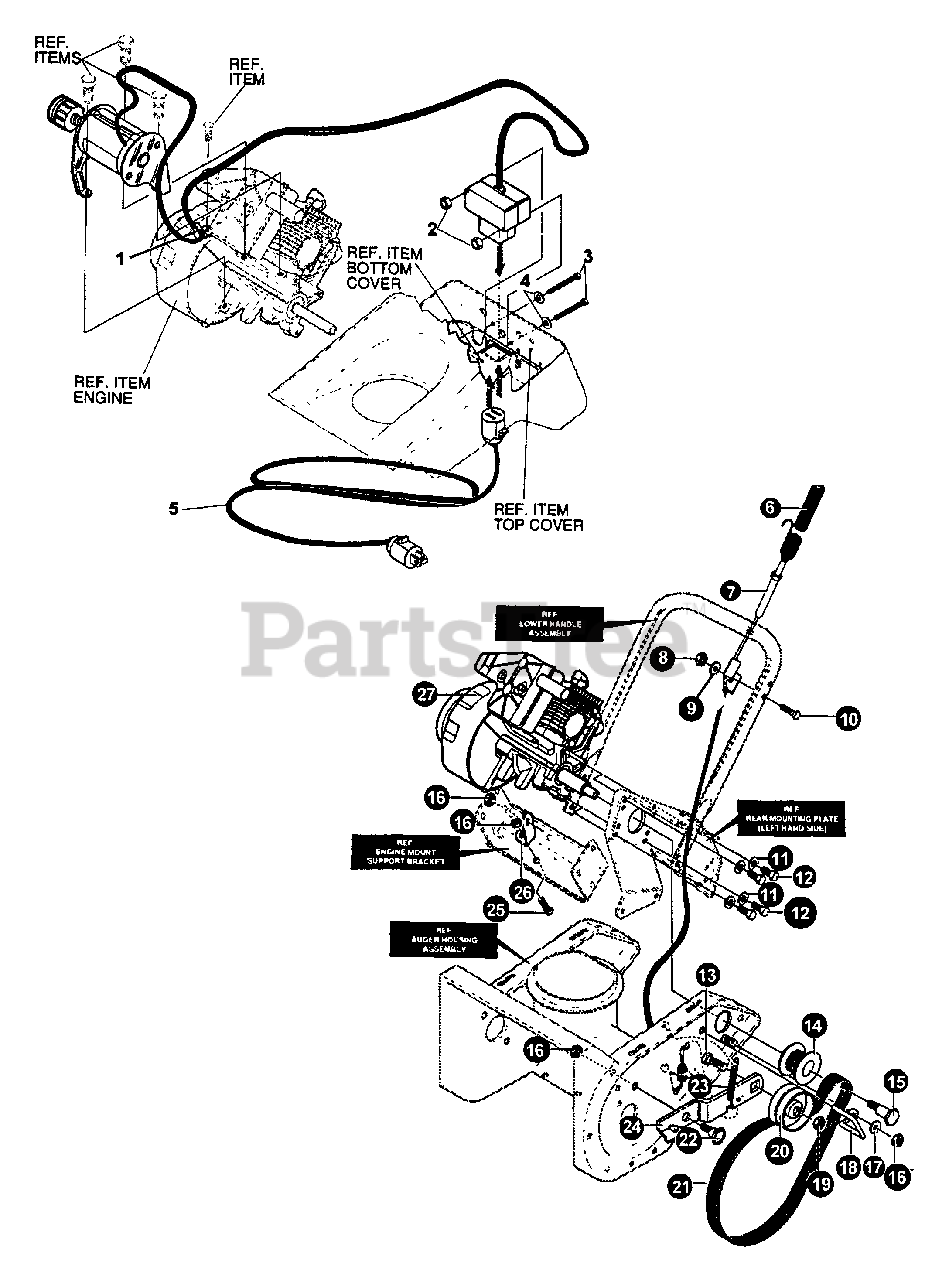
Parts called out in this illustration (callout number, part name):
1	RETAINER, WIRE
2	NUT - 8-32 -- KEPS
3	SCREW - 8-32 X 3"
4	WASHER - .188 X .38 X .040"
5	CORD, EXTENSION 10 FEET
6	COVER, CABLE HOLDER
7	CABLE, DRIVE CONTROL
8	NUT - 1/4-20
9	WASHER
10	SCREW - 1/4-20 X 1-1/2"
11	LOCKWASHER
12	SCREW - 5/16-18 X 3/4"
13	BOLT - 3/8-16 X 1-1/2"
14	PULLEY, 4.5 HP
15	BOLT, SHOULDER .625 X .282
16	NUT - 5/16-18
17	WASHER - .312 X .73 X .065
18	GUIDE, BELT 21"
19	LOCKNUT - 3/8-16
20	PULLEY, IDLER BB 1.88 OD
21	BELT, 10 RIB
22	BOLT, .500 X .177 HHSH 5/16-18
23	SPRING, IDLER BRAKE
24	BRACKET, IDLER ARM
25	SCREW - 5/16-18 X 1/2"
26	SUPPORT, ENGINE
27	ENGINE, 5.0 HP
